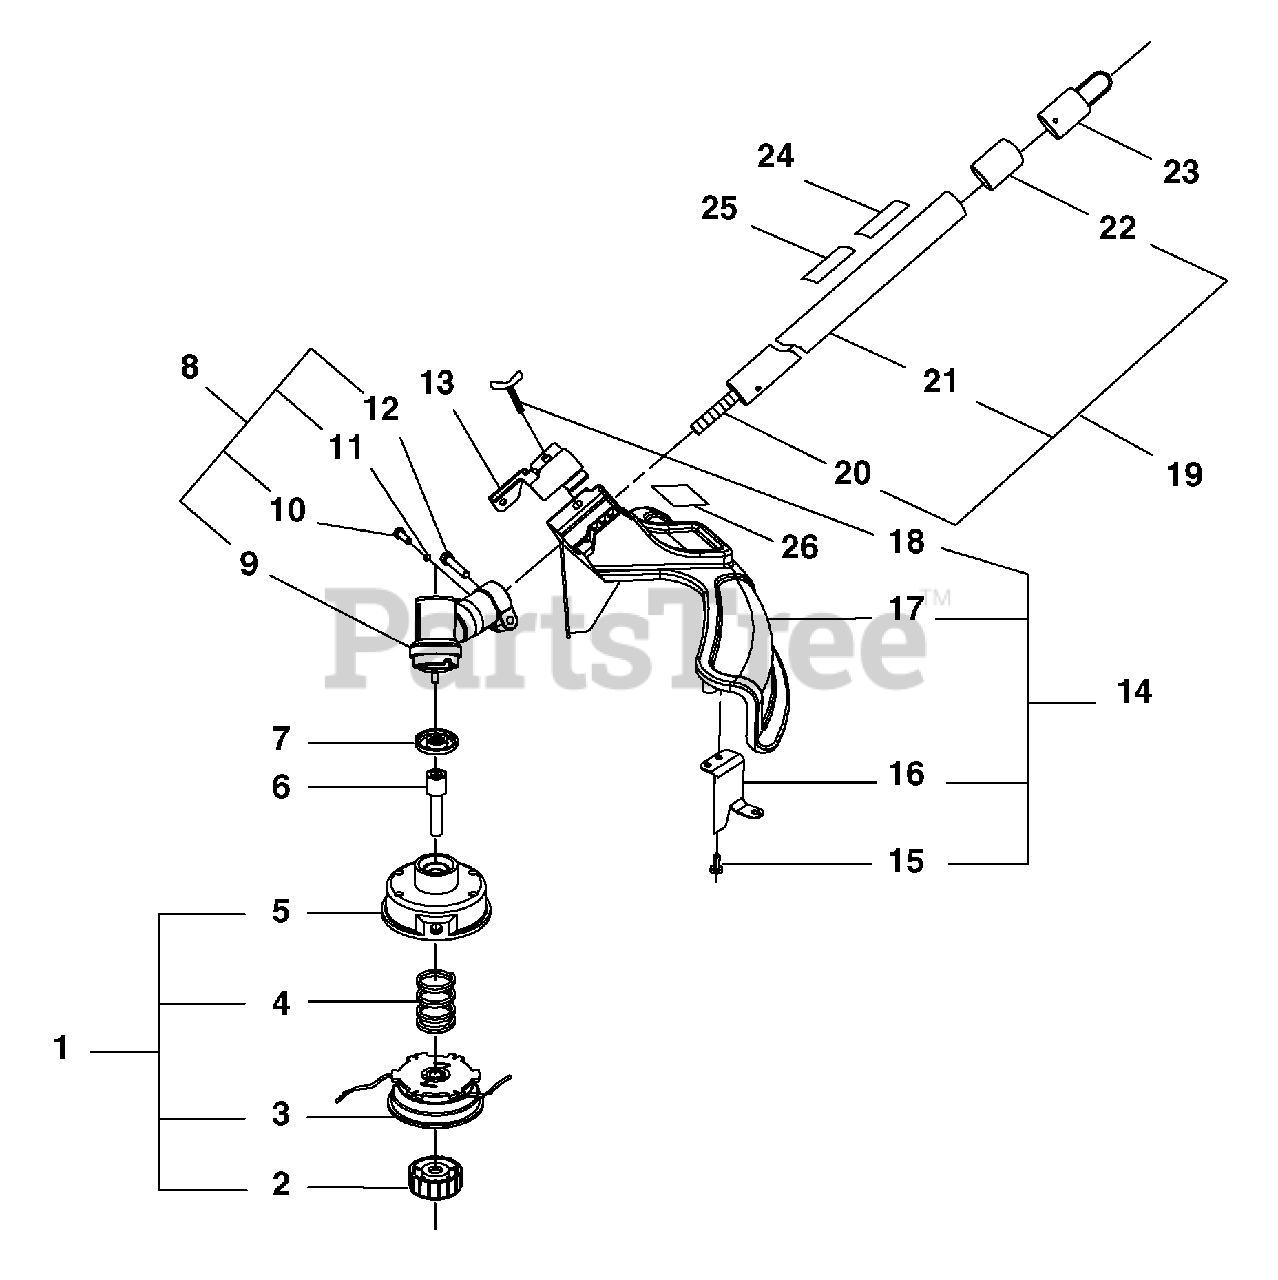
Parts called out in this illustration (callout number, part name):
1	STRINGHEAD ASSEMBLY
2	RETAINER-SPOOL ASSEMBY (L.H.THREAD)
3	SPOOL & STRING ASSEMBLY
4	SPRING-COMPRESSION
5	HOUSING & EYELET ASSEMBLY
6	ADAPTER-STRINGHEAD
7	WASHER-FLANGED
8	GEARHEAD & SCREW ASSEMBLY
9	GEAR HEAD ASSEMBLY
10	HEXAGON HEAD SCREW (M5 X 12 mm)
11	LOCK WASHER (5 mm)
12	CAP HEAD SCREW (M6 X 30 mm)
13	CLAMP FOR GRASS SHIELD
14	BLADE & SHIELD ASSEMBLY
15	PAN HEAD SCREW (ST4.2 X 12 mm)
16	BLADE-CUT OFF
17	GRASS SHIELD
18	WINGED HEAD SCREW (M6 X 30 mm)
19	BOOM ASSEMBLY
20	SHAFT-FLEXIBLE
21	DRIVESHAFT HOUSING ASSEMBLY
22	DUSTPROOF COVER
23	HANGER
24	BRUSH CUTTER KIT WARNING LABEL
25	UL DECAL WARNING LABEL
26	BRAND LABEL
